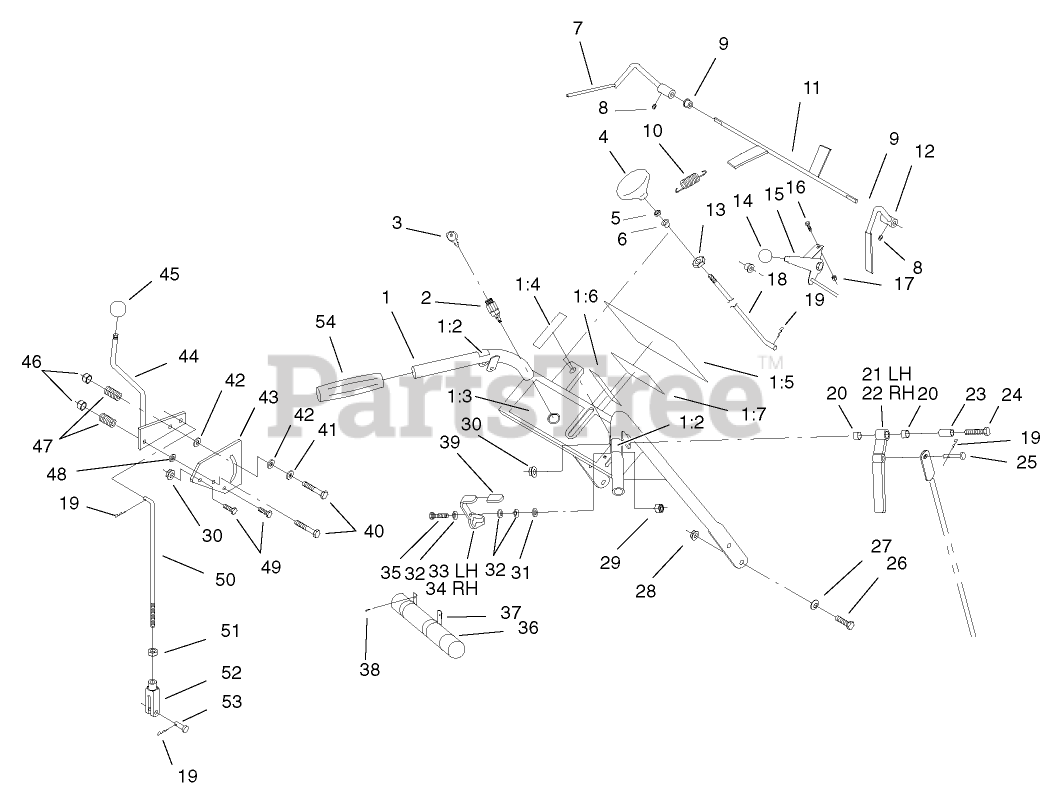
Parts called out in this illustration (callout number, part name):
1	HANDLE ASM
1:2	DECAL-LOCK, NEUTRAL
1:3	DECAL-WARNING
1:4	DECAL-THROTTLE
1:5	DECAL-PROLINE
1:6	DECAL-ENGAGE, DECK
1:7	DECAL-CAUTION, BRAKE
2	SWITCH & KEY (INCLUDES NUT & WASHER)
3	KEY-IGNITION
4	Knob-Push / Pull
5	NUT-JAM
6	Bearing-Nylon
7	LEVER-LH
8	SCREW-SET
9	BUSHING-NYLON
10	SPRING-EXTENSION
11	ROD-CONTROL, OPERATOR PRESENCE
12	LEVER-RH
13	NUT-PUSH
14	KNOB-BALL
15	THROTTLE CABLE ASM
16	BOLT-CARR
17	NUT-LOCK, NI
18	Linkage-Blade
19	PIN-COTTER
20	BUSHING-SLEEVE
21	LH Drive Lever ASM
22	RH Drive Lever ASM
23	Bushing-Lever, Drive
24	SCREW-HH
25	Pin-Clevis
26	SCREW-HH
27	WASHER-BELLEVILLE
28	NUT-HHF, WHIZ
29	NUT-LOCK, NI
30	NUT-HF
31	WASHER-FLAT
32	WASHER-SPRING
33	LATCH-LEVER, LH DRIVE
34	LATCH-LEVER, RH DRIVE
35	SCREW-HH
36	TUBE-MANUAL
37	CLAMP-R
38	SCREW-HWHTF
39	GRIP-LATCH
40	SCREW-HH
41	Washer-Friction
42	Washer-Friction
43	PLATE-LEVER, SHIFTER
44	LEVER-SHIFT
45	KNOB-BALL
46	NUT-LOCK, NI
47	SPRING-COMPRESSION
48	WASHER-PLAIN
49	SCREW-HH
50	Rod-Control, Speed
51	NUT-JAM
52	YOKE-ADJUSTABLE
53	PIN-CLEVIS
54	Grip-Handle
